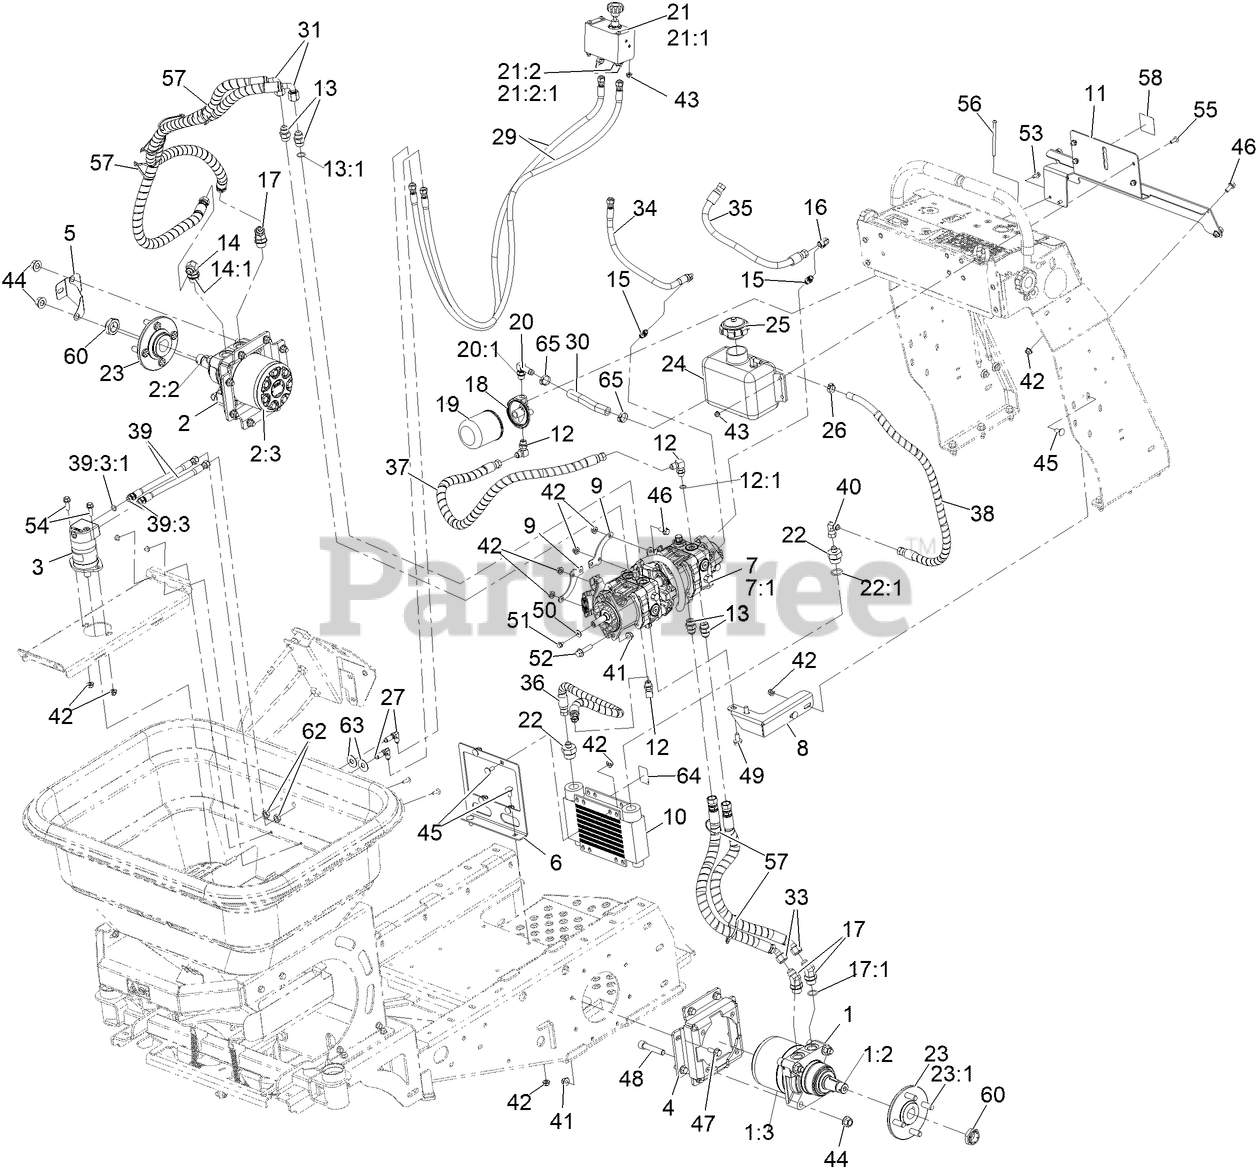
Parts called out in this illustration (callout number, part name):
1	MOTOR, LH WHEEL
1:2	KEY-WOODRUFF
1:3	SEAL KIT
2	MOTOR, RH WHEEL
2:2	KEY-WOODRUFF
2:3	SEAL KIT
3	MOTOR-HYDRAULIC, SPREADER
4	Mount-Motor, Wheel
5	BRACKET-HOPPER, SPEEDOMET
6	Mount-Cooler
7	PUMP-TANDEM
7:1	ASM-AUX PUMP -73054
8	Bracket-Support, Hydro Pump
9	Extension, Hydro Pump
10	COOLER-OIL
11	Mount, Hydraulic Tank And Filter
12	FITTING-ELBOW, 90 DEG
12:1	O-RING
13	FITTING-STRAIGHT
13:1	O-RING
14	FITTING-90 DEG
14:1	O-RING
15	FITTING-STRAIGHT
16	FITTING-90 SWIVEL
17	FITTING-ELBOW, 45 DEG
17:1	O-RING
18	HEAD-FILTER
19	FILTER-25 MICRON, BI-DIRECTIONAL
20	FITTING-ELBOW, 90
20:1	O-RING
21	Manifold-Flow Control, Hopper
21:2	FITTING-ELBOW, 45 DEG
21:2:1	O-RING
22	ADAPTER-STRAIGHT
22:1	O-RING
23	HUB-WHEEL
23:1	STUD-1/2-20 X 1.55
24	TANK-HYDRAULIC, PLASTIC
25	Cap-Vented
26	CLAMP-OETIKER, 167
27	FITTING-ELBOW, 90
29	Hose ASM, HYD HP
30	HOSE-HYDRAULIC
31	HOSE ASM-HYD HP
33	HOSE ASM-HYD HP
34	Hose ASM-HYD HP
35	Hose ASM, HYD LP
36	Hose ASM, HYD LP
37	Hose ASM, HYD LP
38	Hose ASM, HYD LP
39	Hose ASM-HYD HP
39:3	Fitting-Straight, Rigid
39:3:1	O-RING
40	ELBOW-SWIVEL, 90 DEG
41	Nut-Hex Flange
42	Nut-Hex Flange
43	Nut-Hex Flange
44	Nut-Lock 1/2-13
45	SCREW-CARR
46	SCREW-HHF
47	SCREW-HHF
48	Screw-HSH
49	SCREW-HHF
51	SCREW-HHF
52	SCREW-HHF
53	SCREW-HHF
54	SCREW-HHF
55	Screw-Hsbhf
56	Screw-HSBH
57	TIE-CABLE
58	DECAL-OIL
60	LOCKNUT
62	Nut-Jam
63	Washer-SS, 1.25 OD, .503 ID
64	DECAL-WARNING
65	CLAMP-OETIKER, 167
